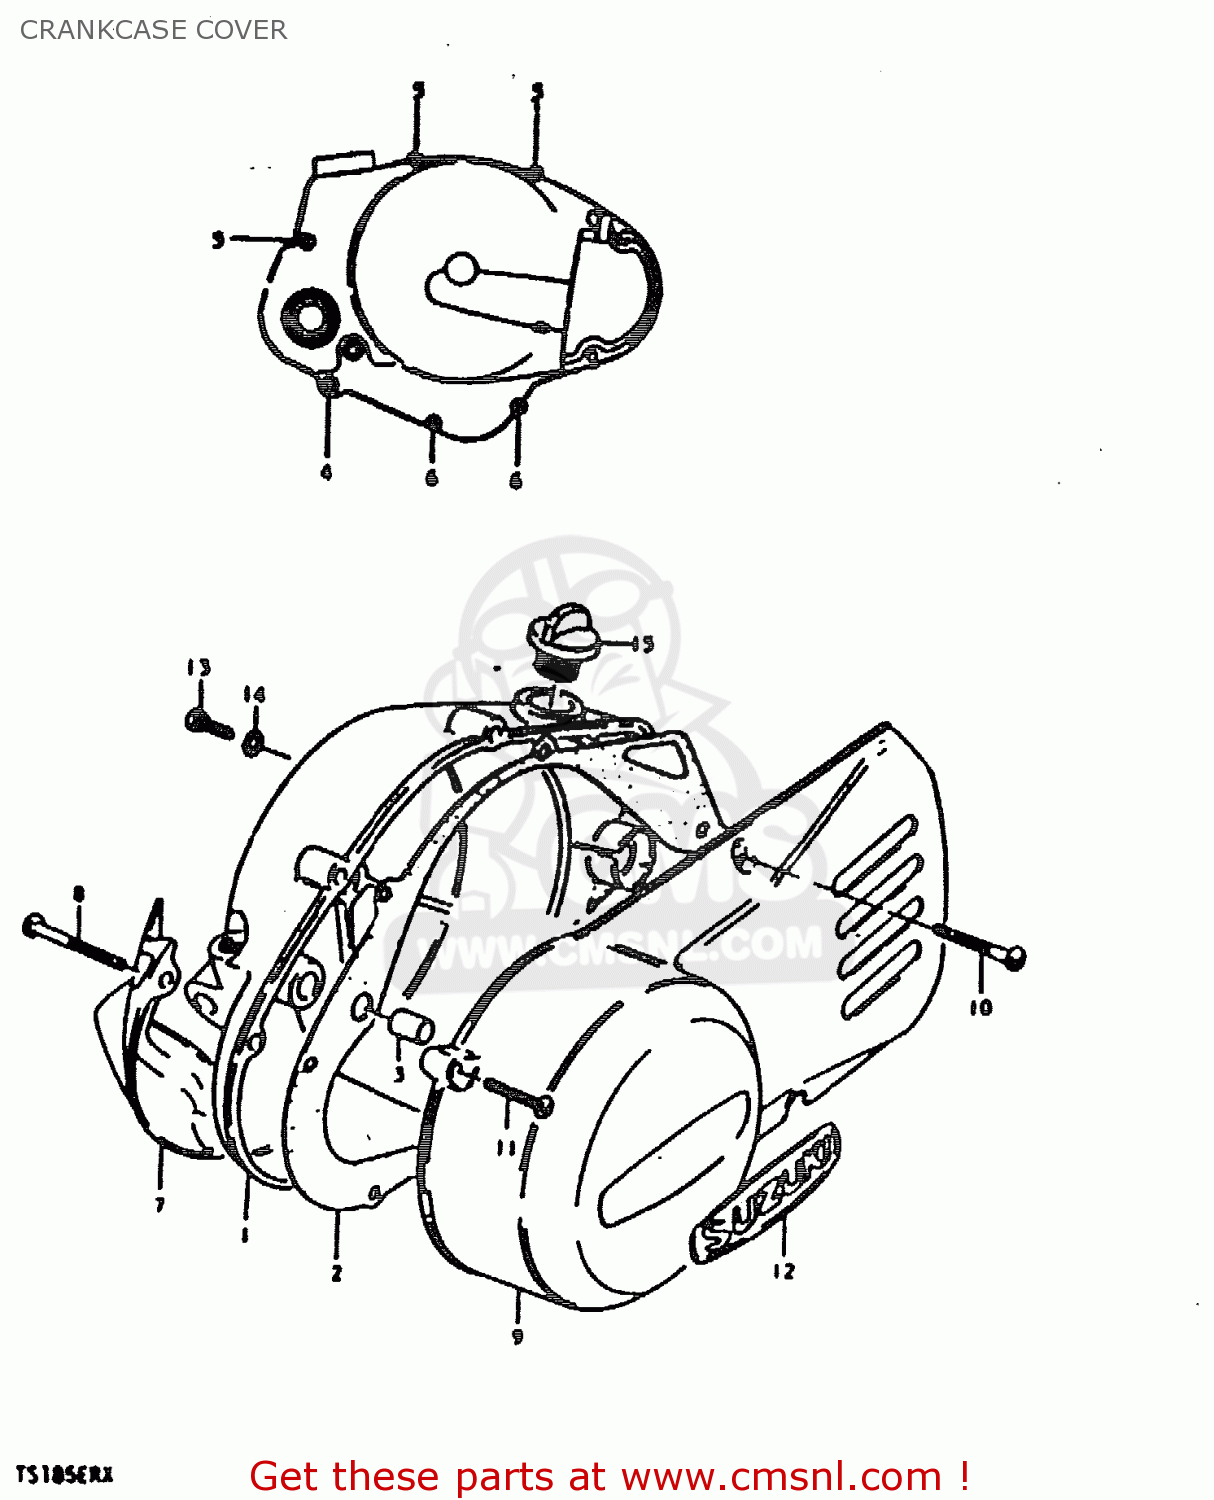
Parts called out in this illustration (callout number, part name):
1	COVER,CLUTCH
2	GASKET,CLUTCH COVER (MCA)
3	PIN
4	SCREW (6X45)
5	SCREW
6	SCREW
7	COVER,CLUTCH RELEASE A
8	SCREW
9	COVER,MAGNETO
10	SCREW 6X30
11	SCREW
12	EMBLEM,MAGNETO COVER
13	SCREW(6X10)
14	GASKET(6.2X11X1) (NAS)
15	PLUG
